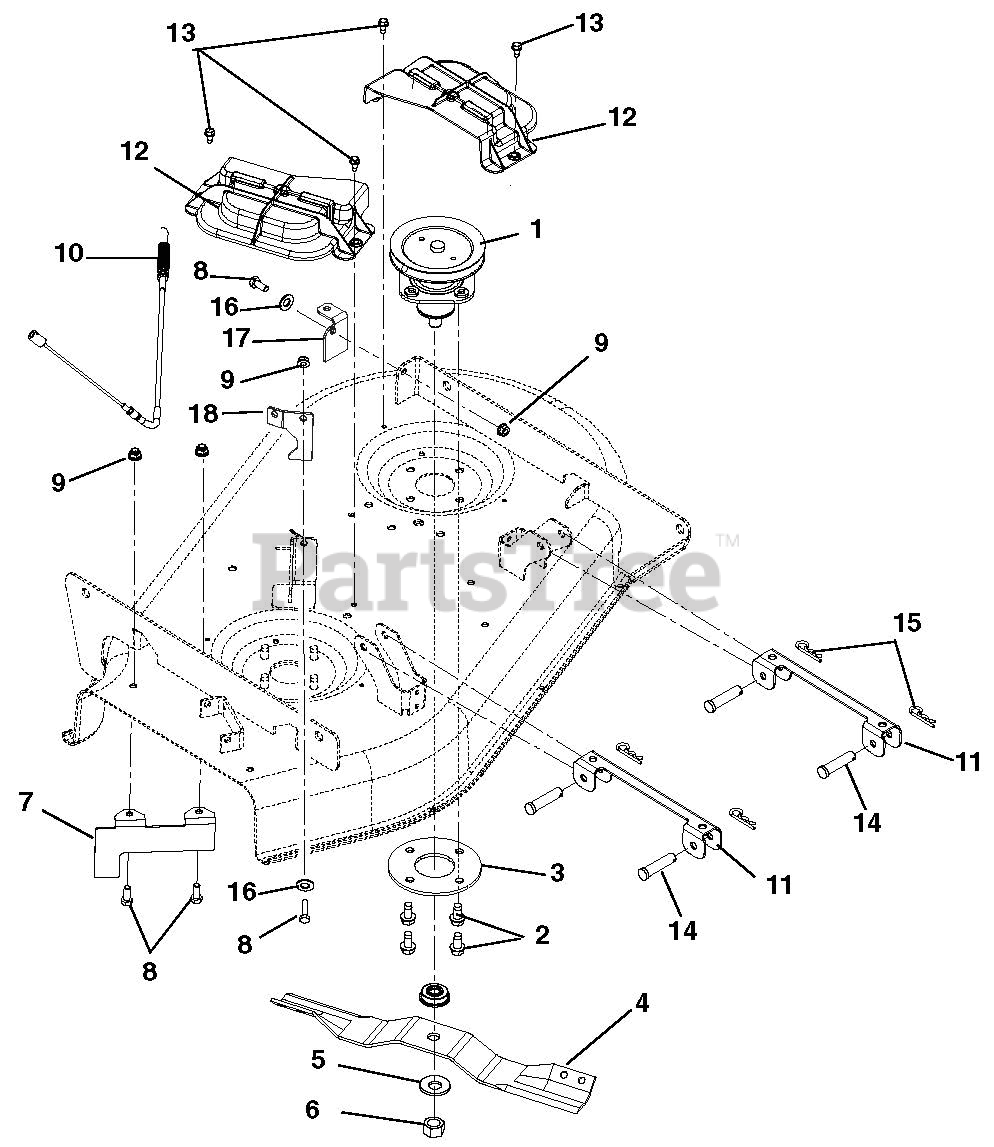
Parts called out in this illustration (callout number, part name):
1	ASSY-SPINDLE
2	@SCR-TAP .38-16X.75 HWH TR YWZ
3	PLATE-REINF, SPINDLE
4	BLADE-17.2" X .156
5	WSHR-BLVL .669X1.535X.138
6	NUT-HEX .62-18 YWZC
7	BRKT-BAFFLE, DISCHARGE 34"
8	@BLT-HEX .31-18X.75 GR5 YWZC
9	@NUT-LK-NYL-FLG .31-18 YWZC
10	CABLE-PTO
11	BRKT-STABILIZER LINK
12	COVER-BELT, MOLDED
13	@SCR-TAP .25-20X.50 HWH TR YWZ
14	PIN-CLEV .375 X 2.00 YWZC
15	PIN,BOW TIE LOCKING .091X1.875
16	@WSHR-FL-STL.38X.875X.083 YWZC
17	BRKT-SPRING ANCHOR
18	BRKT-CABLE MOUNT ADAPTER
